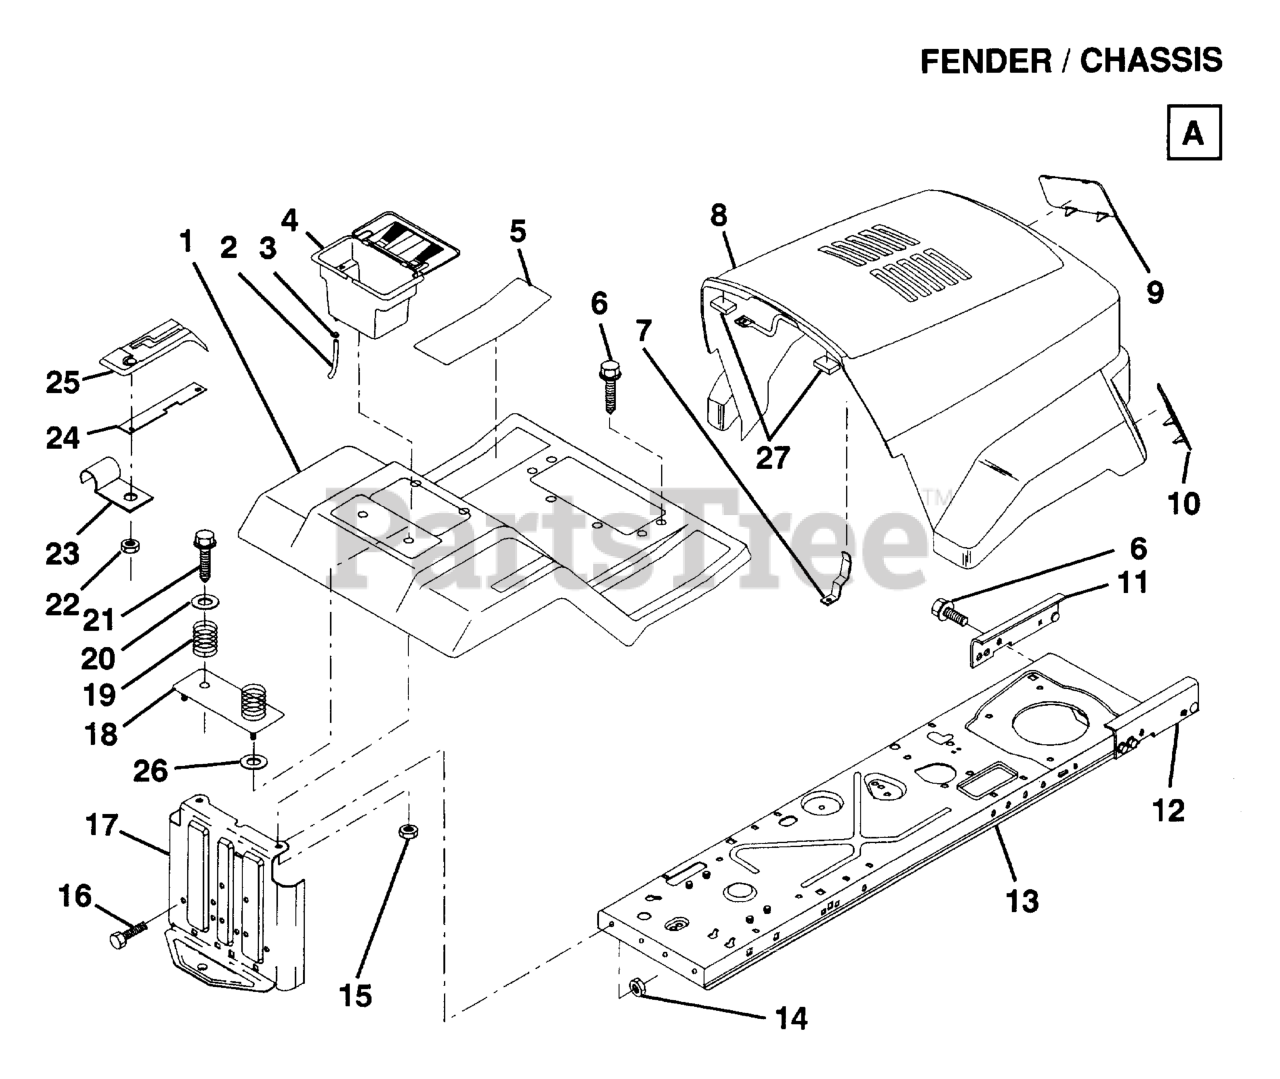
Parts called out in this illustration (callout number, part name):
1	FENDER/FOOTREST
2	TUBE, PLASTIC LT
3	HOSE CLAMP T
4	CASE BATTERY
5	PAD FOOTREST
6	BOLT
7	LATCH HOOD
8	HOOD/GRILL ASSEMBLY
9	LENS.LR.LH.HUSQV.
11	BRK PVT FRAME LH
12	BRK PVT FRAME RH
13	FRAME ASS'Y
14	LOCKNUT
15	NUT
19	SPRING COMPRESSION
20	WASHER
22	NUT.PUSH.3/16
23	CLIP,INSULATOR
24	BAR SHIP LOCK
24	BAR SHIFT LOCK
25	CONSOLE,SHT CONTR
25	CONSOLE SHT CONTR
26	WASHER
27	BUMPER HOOD T
